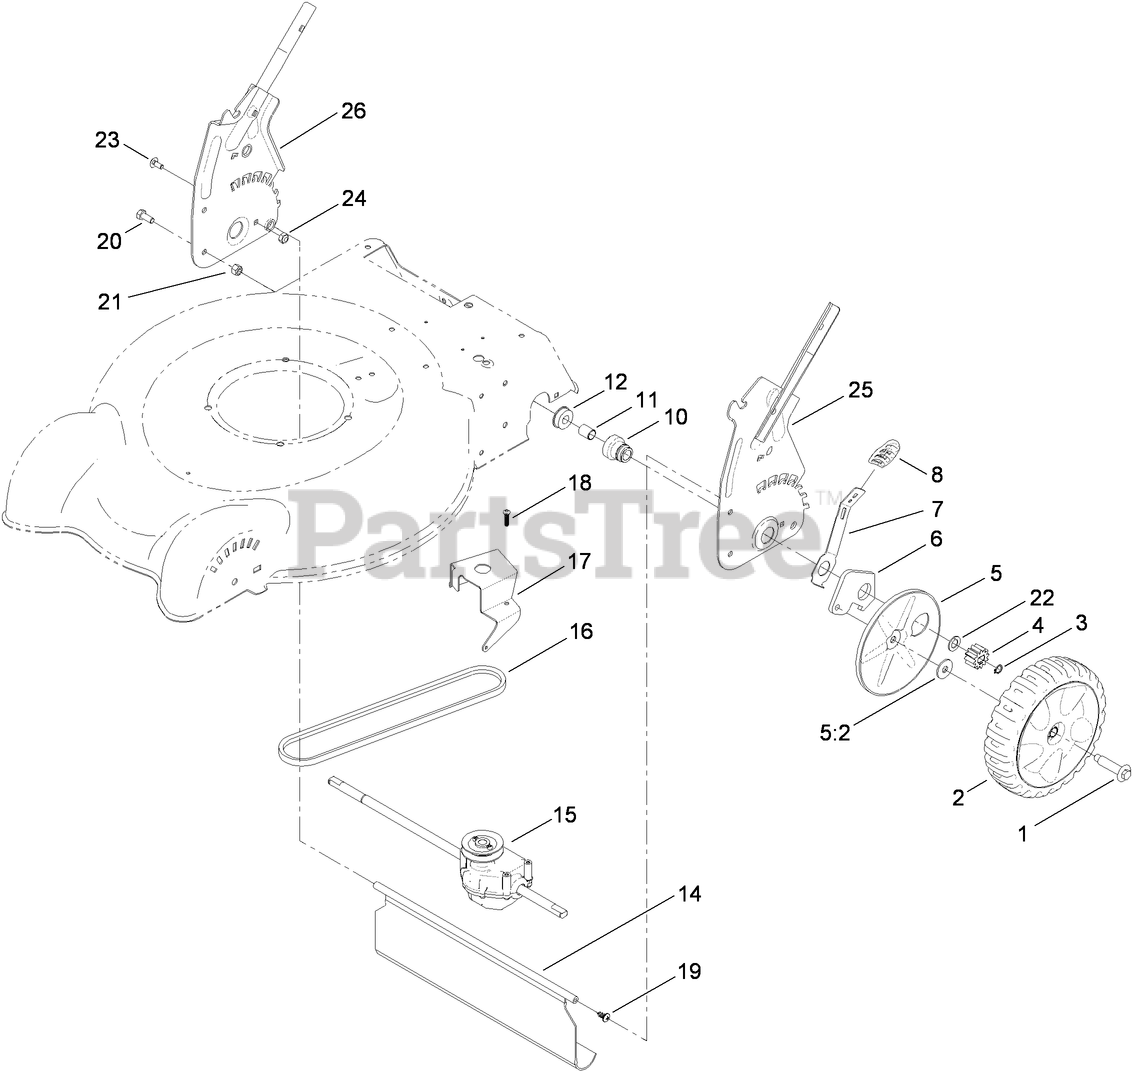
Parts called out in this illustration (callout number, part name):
1	BOLT-SHOULDER
2	8 INCH WHEEL GEAR ASM
3	RING-RETAINING
4	GEAR-PINION
5:2	WASHER-STEPPED
6	ARM-PIVOT, REAR
7	ARM-SPRING
8	KNOB-LEVER, HOC
10	RETAINER-BUSHING, HOC
11	BUSHING-SLEEVE
12	BEARING-BALL
16	V-BELT
17	BRACKET-TRANSMISSION
18	SCREW-PLASTITE
19	SCREW-PTH
20	SCREW-HH
21	NUT-LOCK, NI
22	WASHER-THRUST
23	SCREW-CARR
24	NUT-LOCK, NI
